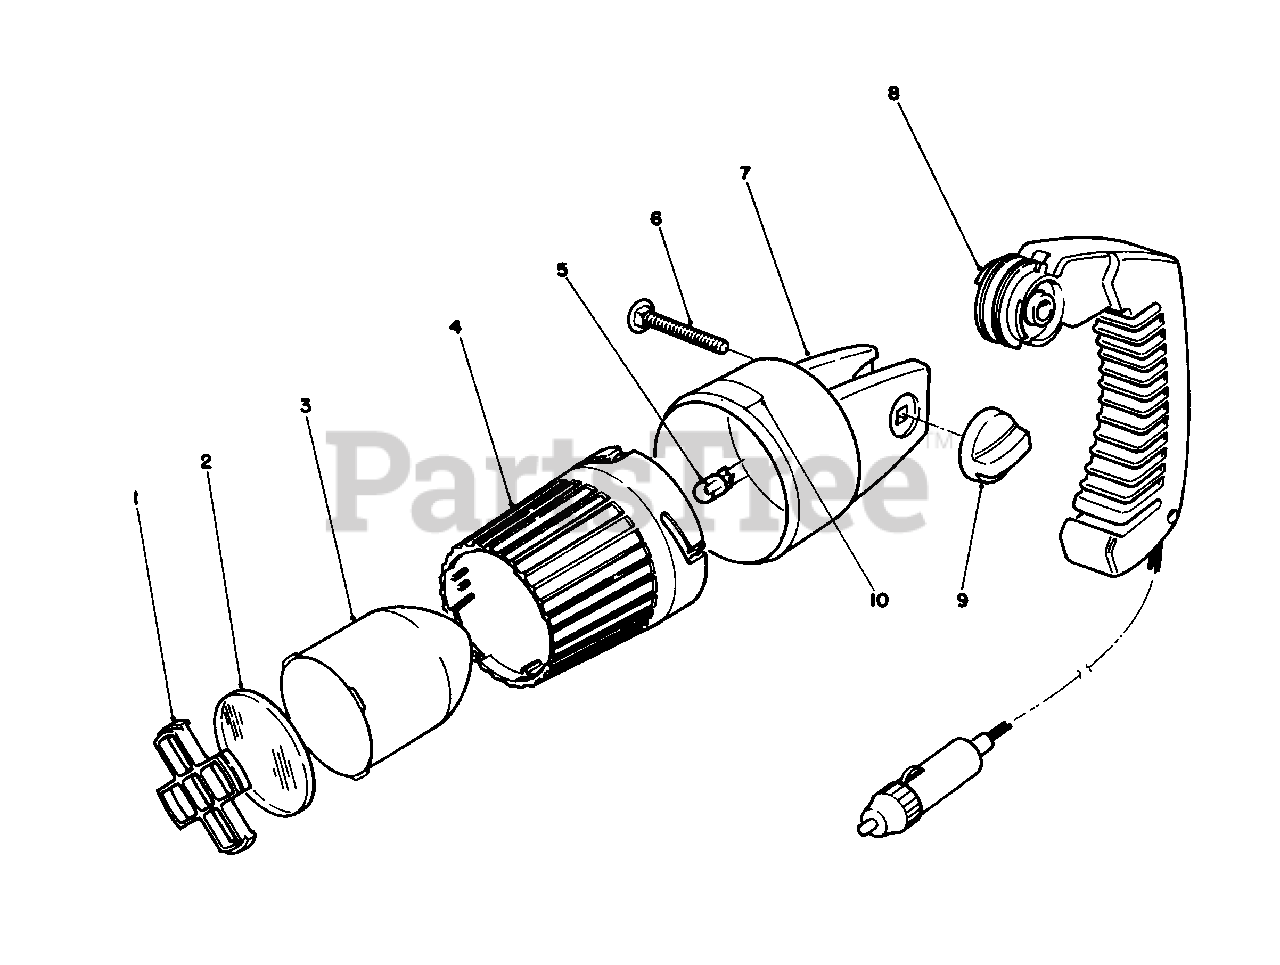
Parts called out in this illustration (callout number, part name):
3	Reflector
4	Ring-Focusing
5	Lamp
6	Bolt-Carriage
7	Housing
8	Handle W/Power Cord
10	Decal-Caution
